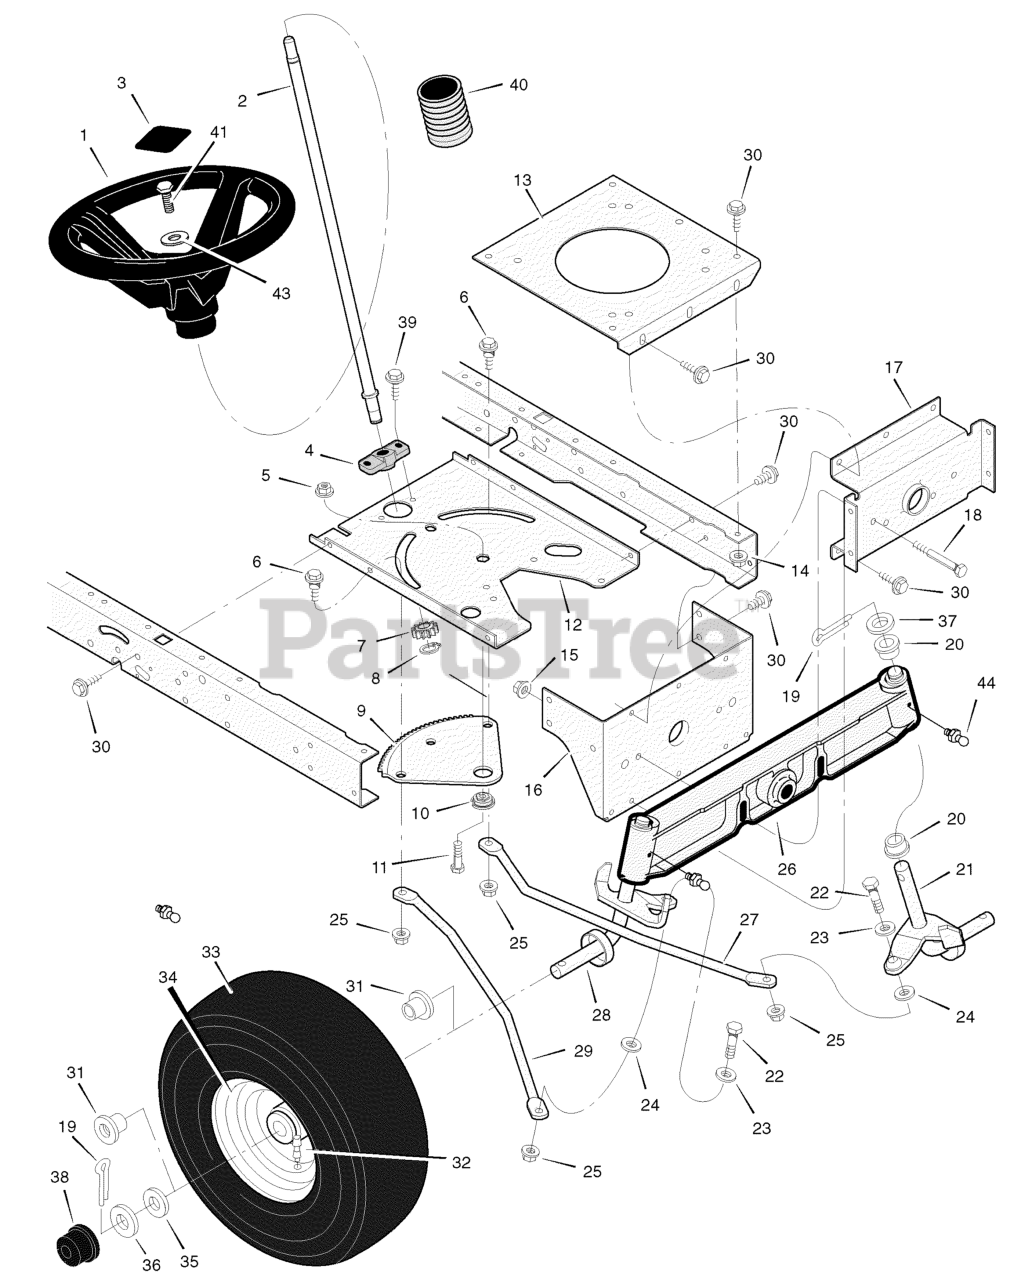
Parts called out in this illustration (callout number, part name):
1	Wheel, Steering
2	Post, Steering
3	Insert, Steering Wheel
4	Bearing
5	Nut, Flange
6	Bolt, Shoulder
7	Gear, Pinion
8	Ring, Snap
9	Gear, Sector
10	Bearing
12	Plate, Steering
13	Plate, Engine
14	Nut, Flange
15	Nut, Flange
16	Bracket, Hanger
17	Axle, Hanger
18	Bolt
19	Pin, Cotter
20	Bearing
21	Spindle Assembly, Left
22	Bolt
23	Washer
24	Washer
25	Nut, Flange
26	Axle Assembly
27	Drag Link, Left
28	Spindle Assembly, Right
29	Drag Link, Right
30	Screw
31	Bearing, Wheel
32	Stem, Valve
33	Tire *
34	Wheel & Tire Assembly *
35	Washer
36	Washer
37	Washer
38	Hub Cap
39	Screw
40	Bellows
41	Screw, Hex
43	Washer
44	Fitting, Lub
